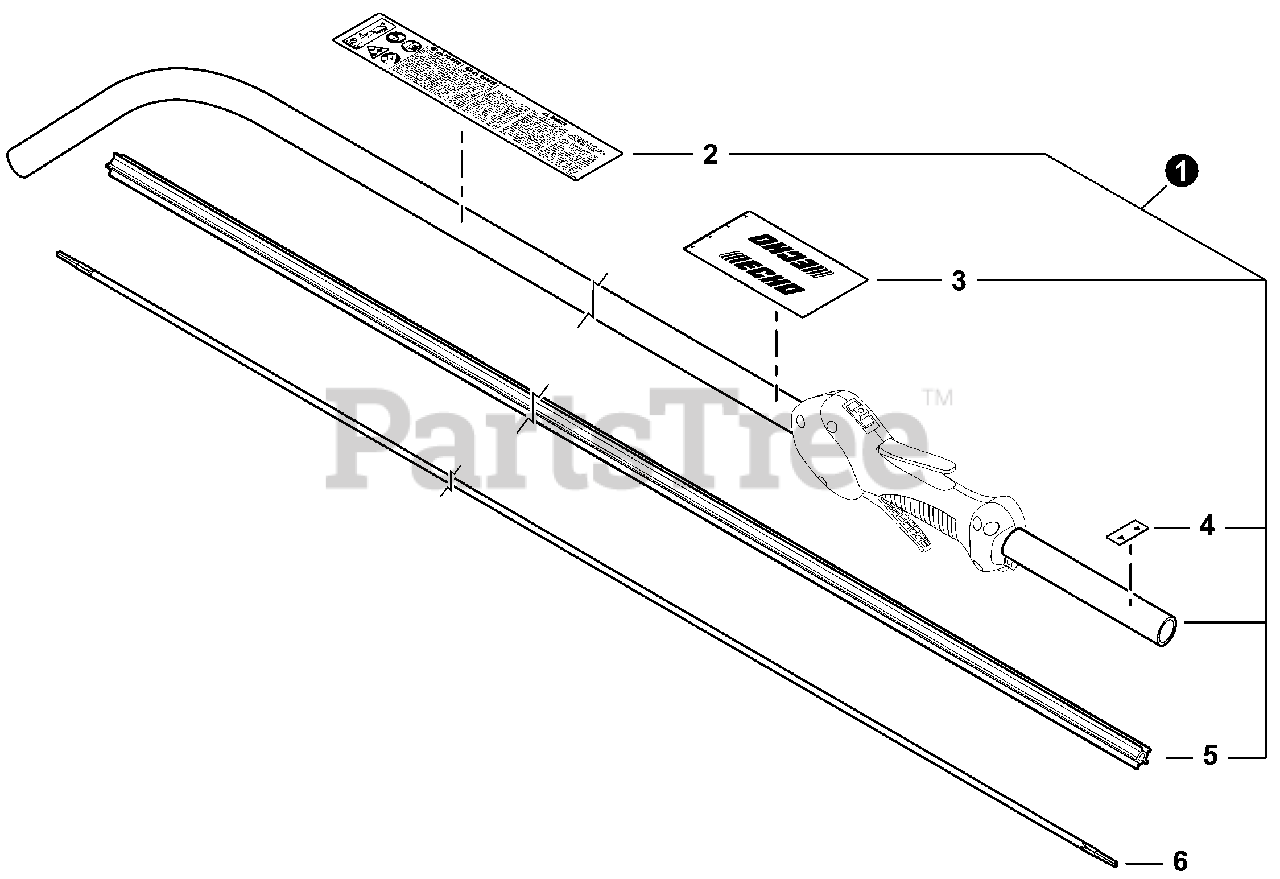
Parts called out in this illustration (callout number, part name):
1	MAIN PIPE ASSY
2	LABEL, CAUTION
3	LABEL, HANDLE LOCATION
4	LABEL - ALIGNMENT
5	LINER - FLEXIBLE
6	DRIVESHAFT - FLEXIBLE
